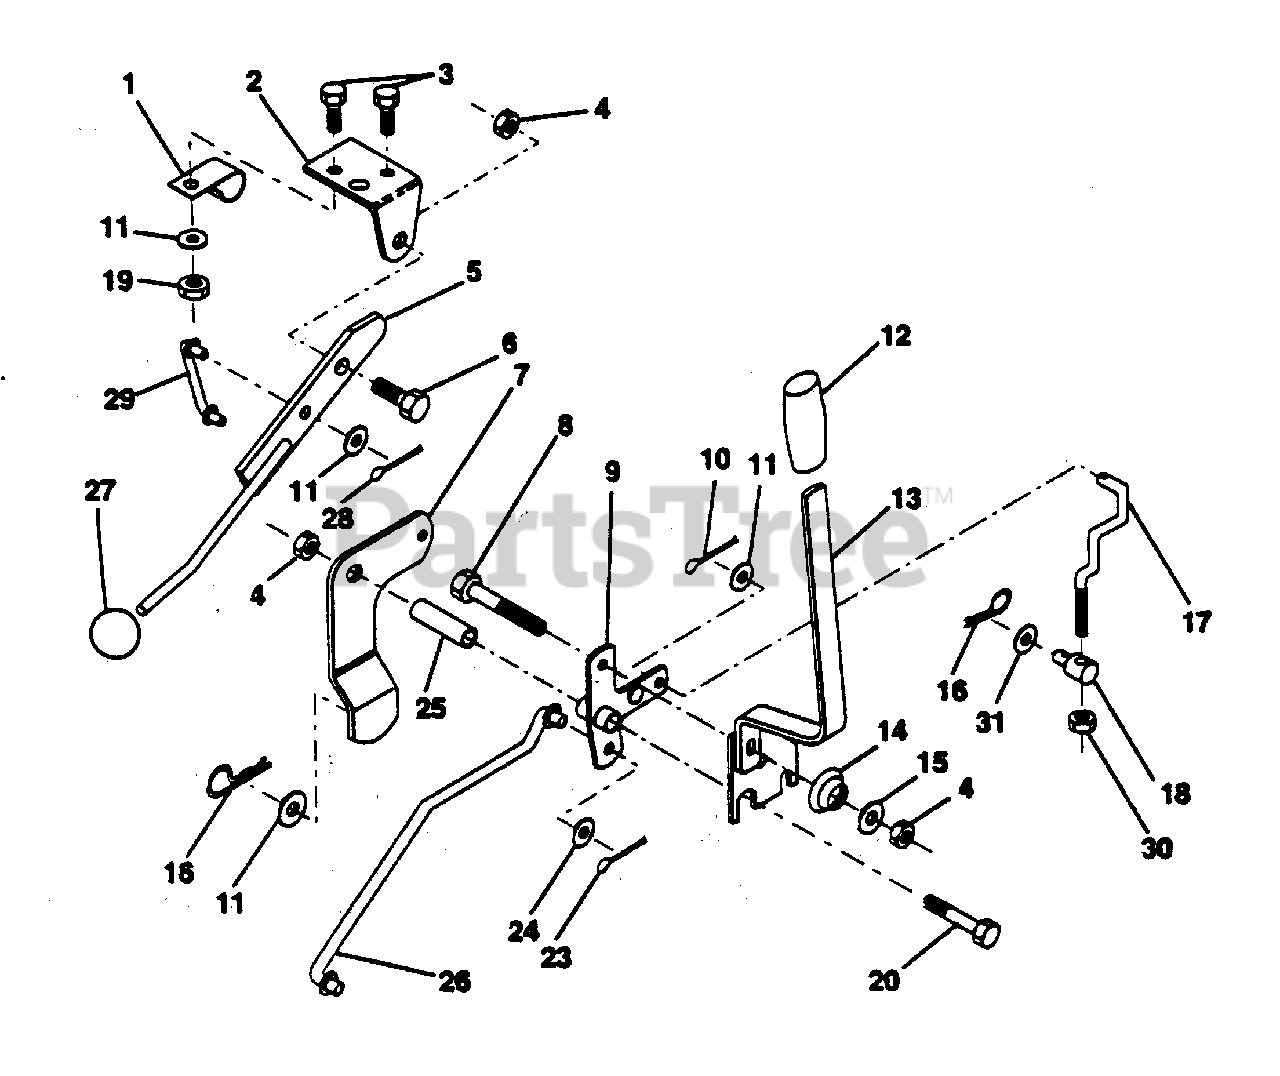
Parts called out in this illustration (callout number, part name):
1	Clip, Insulated (AYP part number)
2	Bracket, Mower Clutch (AYP part number)
3	Bolt, Fin. Hex 1/4-20 UNC x 1/2 Gr. 5 (AYP part number)
4	Nut, Crownlock 3/8-16
5	Assembly, Clutch Lever (AYP part number)
6	Bolt, Shoulder (AYP part number)
7	Assembly, Mower Clutch Arm (AYP part number)
8	Bolt, Hex 3/8-16 UNC x 2-1/4 (AYP part number)
9	Assembly, Bellcrank Lift (AYP part number)
10	Pin, Cotter 1/8 x 3/4 (AYP part number)
11	Washer 13/32 x 13/16 x 16 Ga. (AYP part number)
12	Grip, Handle
13	Assembly, Lift Handle (AYP part number)
14	Spring, Compression (AYP part number)
15	Washer 13/32 x 3/4 x 12 Ga. (AYP part number)
16	Retainer, Spring (AYP part number)
17	Link, Front Lift (AYP part number)
18	Trunnion, Threaded 3/8-16 (AYP part number)
19	Nut, Crownlock 1/4-20 (AYP part number)
20	Bolt, Fin. Hex 3/8-16 UNC x 2-3/4 (AYP part number)
23	Pin, Cotter 1/8 x 1 (AYP part number)
24	Washer 17/32 x 1 x 12 Ga. (AYP part number)
25	Tube, Spacer (AYP part number)
26	Rod, Mower Lift (AYP part number)
27	Knob (AYP part number)
28	Pin, Cotter 3/32 x 3/4 (AYP part number)
29	Link, Mower Clutch (AYP part number)
30	Nut Hex Jam 3/8-16 x 1.30 (AYP part number)
31	Washer 13/32 x 1-1/4 x 12 Ga. (AYP part number)
